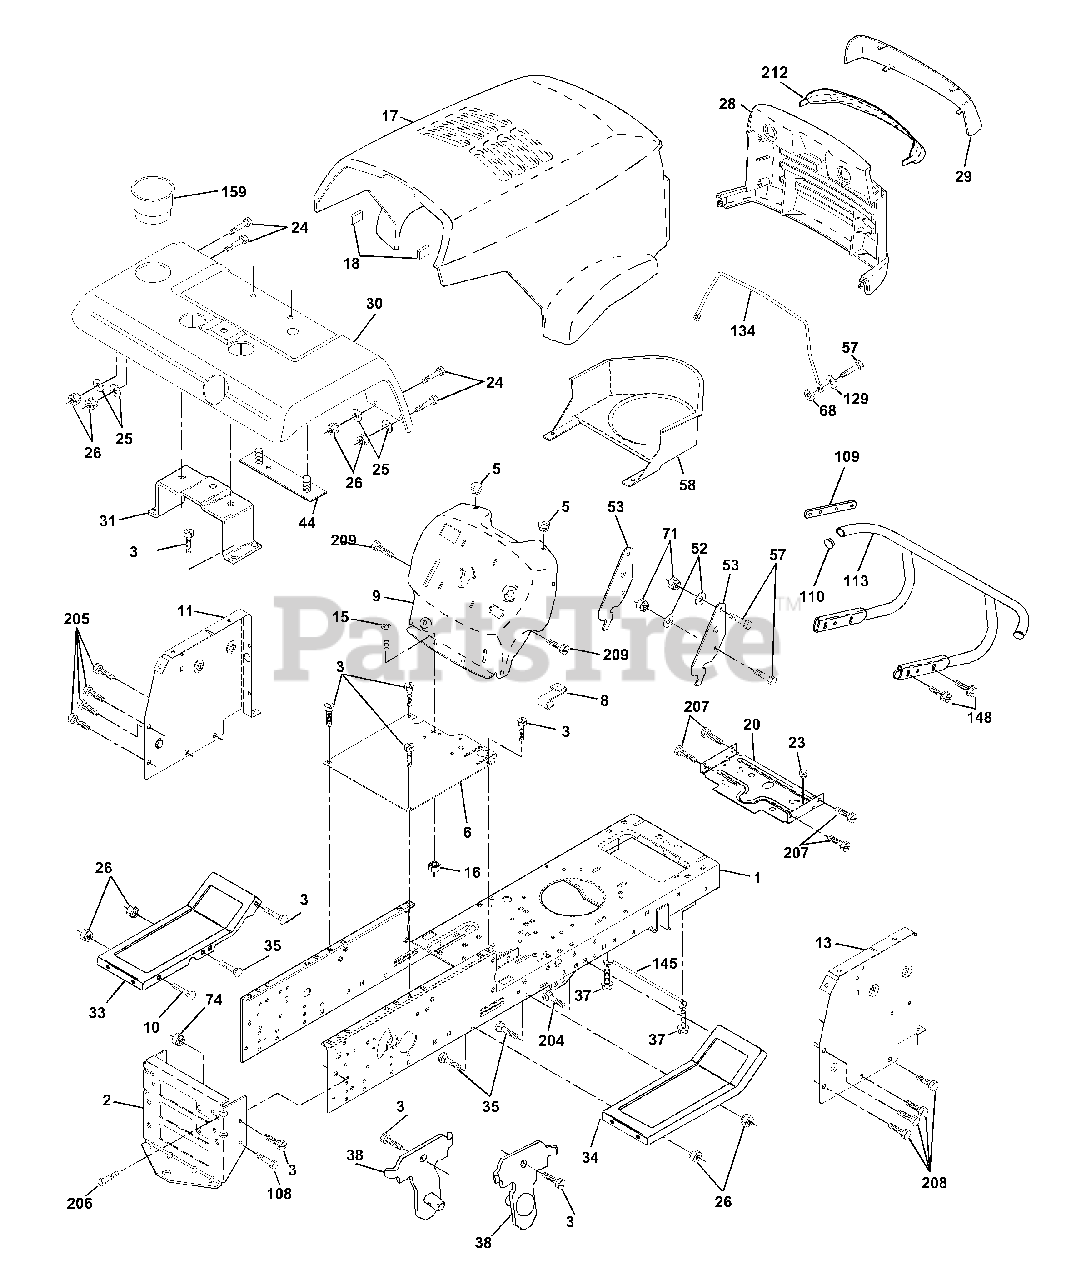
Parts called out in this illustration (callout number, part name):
1	Chassis Stamping
2	Drawbar
3	Screw 3/8-16x3/4
8	Clip Insulator
10	Bolt Rdhd Sqnk 3/8-16 Unc x 1
11	Panel Asm.
13	Panel Asm.
15	Screw Mach Trhd 5/16-18 Unc x 3/4
16	Nut Keps 5/16-18 Unc
17	Hood
20	Plate Mtg Battery/Fuel Tank
24	Bolt 3/8-16 Unc x 1 Gr. 5
25	Washer 13/32 x 13/16 x 12 Ga.
26	Nut Lock w/Insert 3/8-16 UNC
28	Grille
29	Grille Lens
30	Fender
31	Bracket
33	Foot Rest, L.H.
34	Foot Rest, R.H.
35	Bolt Rdhd Sht Sqnk 3/8-16 x 3/4
37	Screw Thdrol 5/16-18 x 1/2
38	Bracket Asm Pivot Mower Rear
44	Strap Asm. Fender
52	Washer 9/32 x 7/8 x 16 Ga.
53	Bracket LT/PL Husq.
57	Bolt Fin Hex 1/4-20 Unc x 3/4
68	Nut Keps 1/4-20 UNC
71	Nut Crownlock 1/4-20 UNC
74	Nut, Crownlock 3/8-16 UNC
108	Hex Bolt 3/8-16 UNC x 3/4
109	Bracket Extension Bumper
110	Plug Plastic
113	Bumper Asm.
129	Washer 9/32 x 5/8 x 16 Ga.
134	Rod Support Hood
145	Rod Pivot Chassis Hood
148	Screw 3/8-16 x 1-1/4
159	Cupholder YTGT Grey
206	Bolt Shoulder 5/16-18 TT
207	Screw Thdrol 5/16-18 x 1/2 TYTT
208	Screw Thdrol 3/8-16 x 1/2 Ty-TT
209	Screw Hex Wsh Thdr 3/8-16 x 3/4
212	Insert Lens Reflect
